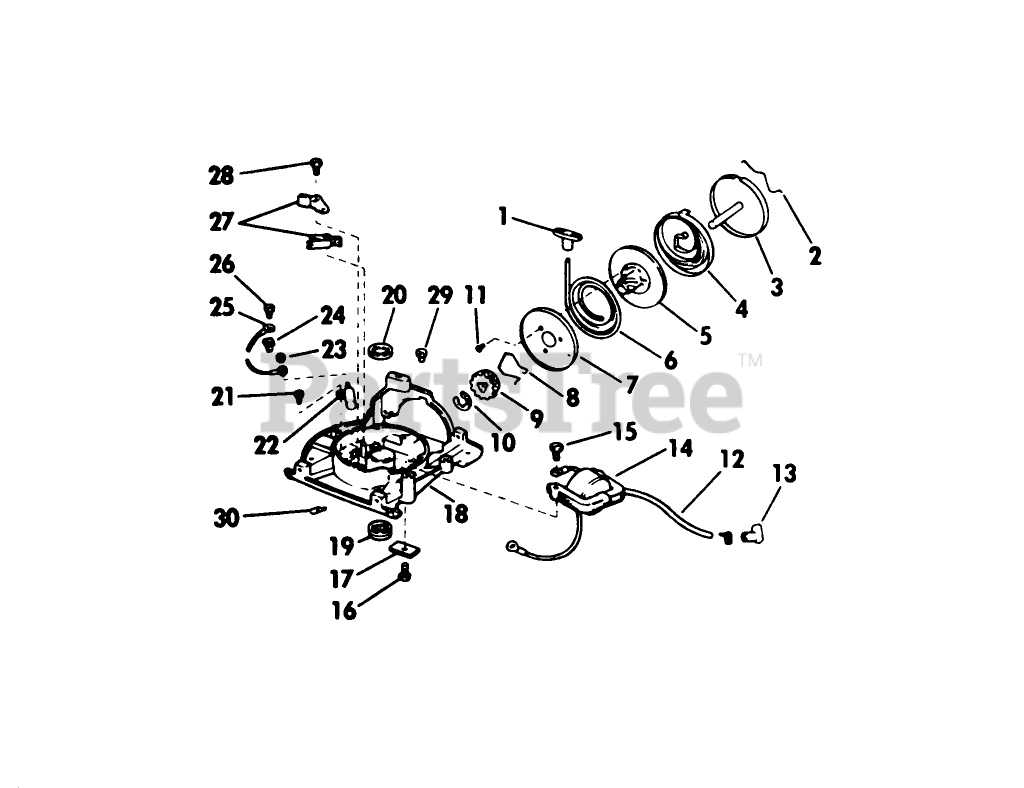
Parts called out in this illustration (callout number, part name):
2	SPRING S
4	SPRING S
8	STARTER SPRING S
9	STARTER PINION S
11	SCREW S
12	LEAD AY. S
16	SCREW S
19	BEARING AY. S
24	NUT - CLIP
27	BREAKER AY. S
31	WASHER S
